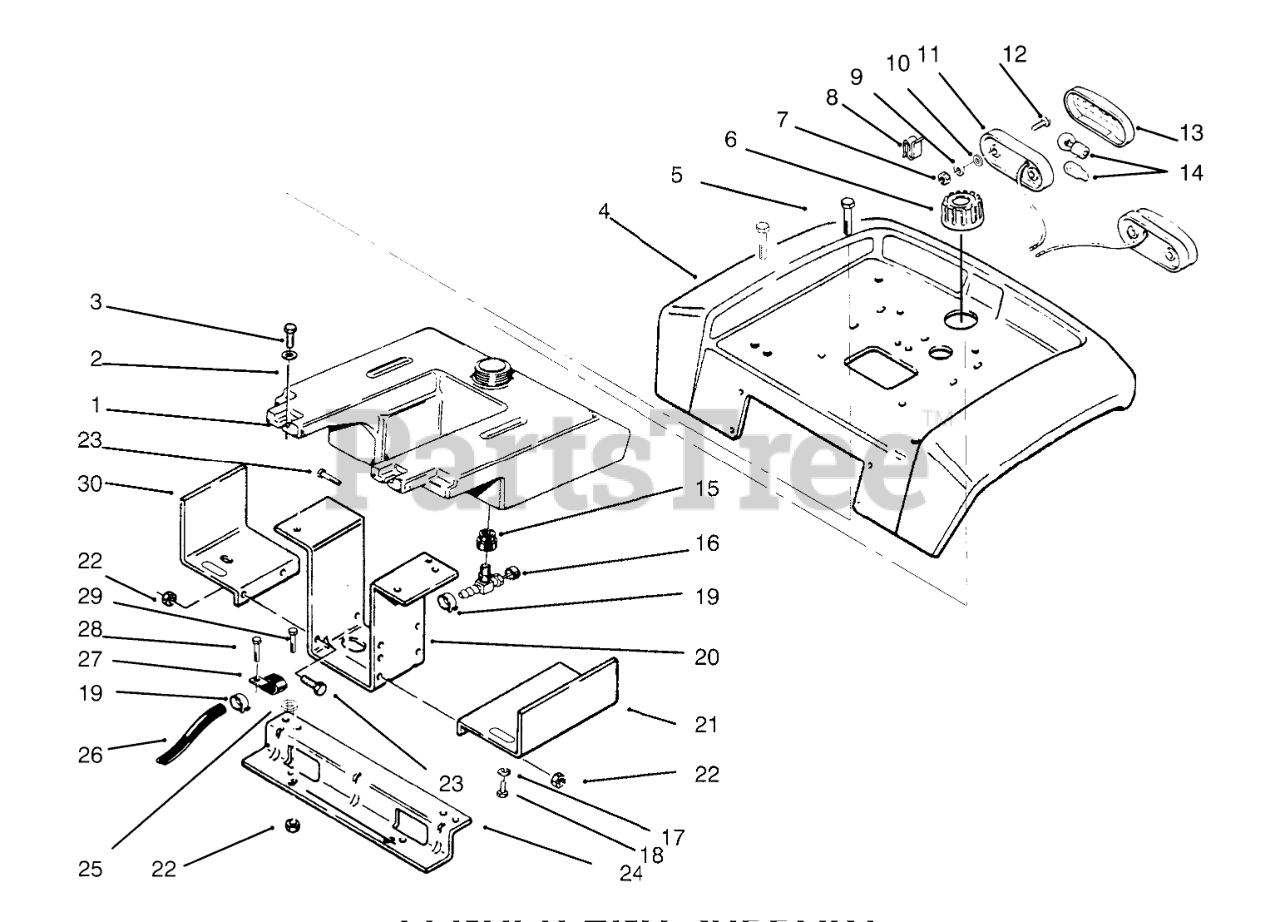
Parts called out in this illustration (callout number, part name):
1	TANK-FUEL
2	WASHER-FLAT
3	Bolt
4	Fender
5	SCREW
6	GAS CAP ASM
7	NUT-LOCK, NI
8	SPEED CLIP
9	WASHER-FLAT
10	WASHER-LOCK, INT
11	BASE-TAIL LIGHT
12	Screw
13	LENS-TAIL LIGHT
14	Bulb
15	BUSHING
16	VALVE-FUEL
17	WASHER-LOCK
18	SCREW-HH
19	CLAMP-HOSE
20	Bracket-Fender
21	Fuel Tank Support LH
22	NUT-LOCK, NI
23	SCREW-HH
24	BRACKET-FENDER B
25	WASHER-PLAIN
26	Line-Fuel 62"
27	CLIP
28	SCREW-HH, LOCK
29	SCREW-HH
30	Support-FueITank RH
